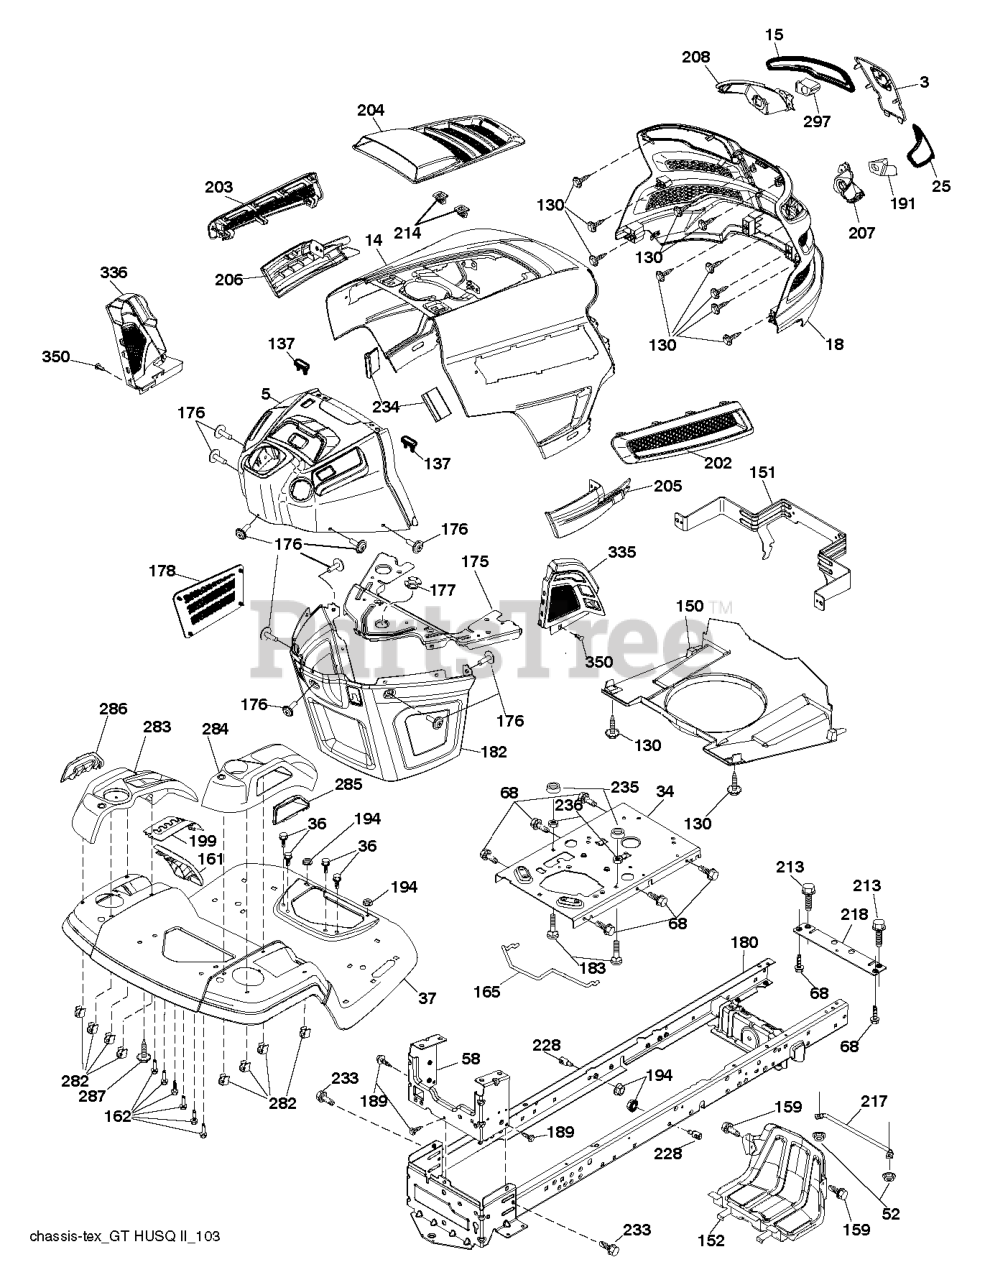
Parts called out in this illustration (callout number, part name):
3	APPLIQUE.SUBASM.GT.HUSQ.II
5	DASH.UPP.GT2.DUAL.RD.PTO.MCHOK
14	HOOD.ASM.HUSQVARNA.GT.TEX.422
15	LENS.HEADLIGHT.LH.GTII.2011
18	GRILLE.SUBASM.GT.HUSQ.II
25	LENS.HEADLIGHT.RH.GTII.2011
34	PLATE.ENGINE.WELDED.CHASSIS
36	SCREW 5/16"
37	FENDER.TLT.FS.W/CPH/FW/RSF.ORN
52	LOCKNUT
58	DRAWBAR UPPER 2PC SMALL FENDER
68	Screw 5/16-18 x 1/2 Hex, Self Tapping 5/16-18 x 1/2
130	SCREW.#10 X 0.750.BOS
137	BUMPER DASH
150	AIR.DUCT.GTV.BLACK
151	BRACKET.PIVOT.HOOD.GT.HUSQ.II
152	SHIELD.BROWNING.PNT.GT.V2
159	SCREW, 3/8-16X3/4
161	WINDOW FUEL
162	SCREW.HI-LO.CONSOLE
165	SUPPORT.TANK.REAR.W/TEX
175	PLATE.CROSSMEMBER.HUSQ
176	SCREW.#10-24X5/8.RN.QU
177	BUSHING, STEERING
178	CARGO.ASM.NET.TXGT.W/C
180	CHASS.WLDMNT.TL.12GA/2P.48/54
182	DASH.LOWER.COMMON.12V.ADAPTOR
183	BOLT.5/16-18X1-1/4 FULL THD
189	SCREW
191	INSERT.REFLECTIVE.RH.HUSQ.GTII
194	NUT LOCK HEX FLANGE 5/16-18
199	PLATE.DECK.LIFT.HUSQ.LT
202	VENT.SIDE.RH.GT.HUSQ.II.
203	VENT.SIDE.LH.GT.HUSQ.II.498
204	VENT.TOP.HUSQ.GT2
205	SIDE.TRIM.RH.GT.HUSQ.II
206	SIDE.TRIM.LH.GT.HUSQ.II.GRAY
207	BEZEL LIGHT.RH.GT.II.MYLAR
208	BEZEL LIGHT.LH.GT.II.MYLAR
213	BOLT
214	CLIP.RETAINER.TINNER.
217	ROD.PIVOT.HOOD
218	X-PIECE.HOOD.STOP.NON/
228	STUD.FASTNER.W/ANTI-ROTATE
233	BOLT.SHOULDER
234	BUMPER.HOOD.TEX.HUSQVARNA
235	SPACER FENDER
236	NUT.CENTERLOCK.5/16-
282	CLIP.RETAINER.CONSOLE.LT.HUSQ
283	CONSOLE.DECK.LFT.R.SDFL.HUSQLT
284	CONSOLE.CNTRL.
285	CONSOLE INSERT RH
286	CONSOLE.INSRT.LH.HUSQ.LT.BLACK
287	SCREW 1/4X20
297	INSERT.REFLECTIVE.LH.HUSQ.GTII
335	COVER.LOWER.DASH.RH.BLACK
336	COVER.LH.CLOSE.OUT
350	CLIP.X-MAS.TREE
